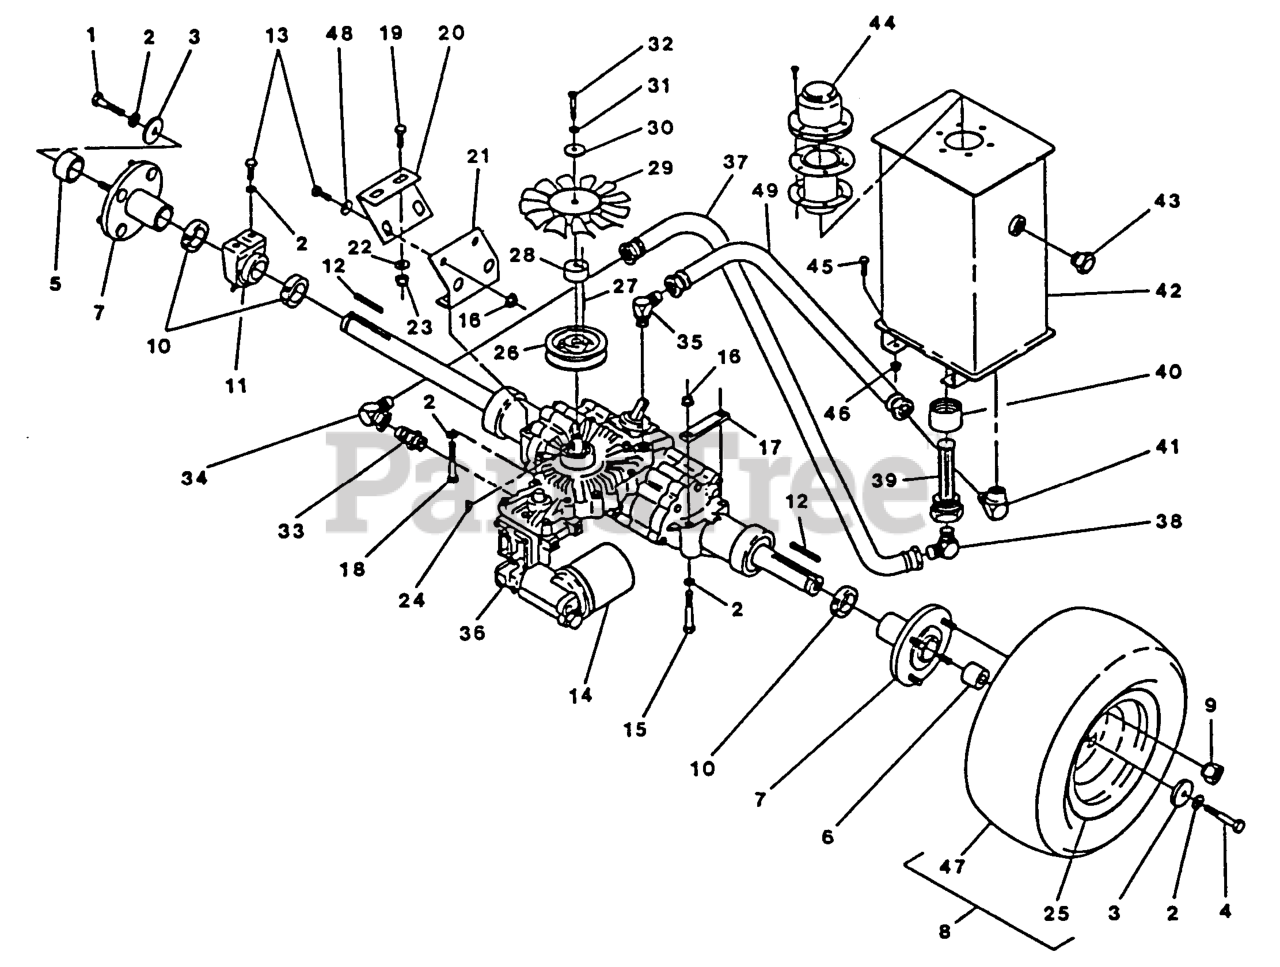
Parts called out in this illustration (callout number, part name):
8	WHEEL AND TIRE ASM
11	BEARING,PILLOW BLOCK
12	KEY,MACH HRD
28	SPACER,FAN
29	FAN,7"OD/10BLADE
30	WASHER-RETAINER, PULLEY
31	WASHER-LOCK
40	COUPLING,1 1/4 NPT
41	FEMALE 90 DEG ELBOW
43	SIGHT-CHECK
44	BREATHER,FILLR & CAP
